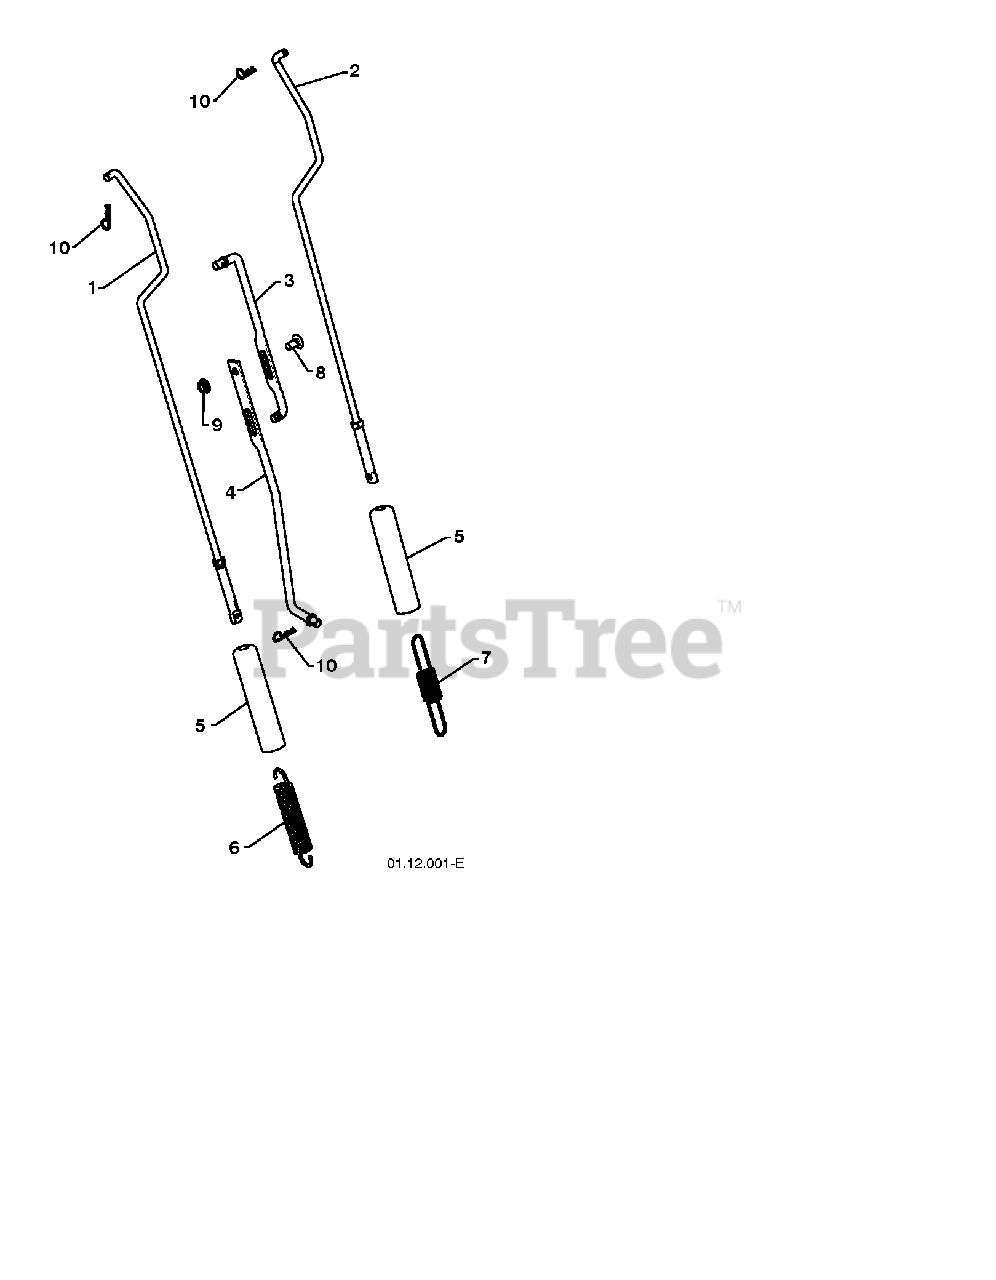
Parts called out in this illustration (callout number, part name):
1	ROD.ASM.IMPELLER
2	ROD.ASM.TRACTION
3	ROD, UPPER SPEED CONTROL
4	ROD, LOWER SPEED CONTROL
5	SLEEVE, SPRING
6	SPRING, AUGER CONTROL
7	SPRING, TRACTION DRIVE
8	BOLT
9	NUT.FLANGE.5/16
10	SPRING RETAINER
